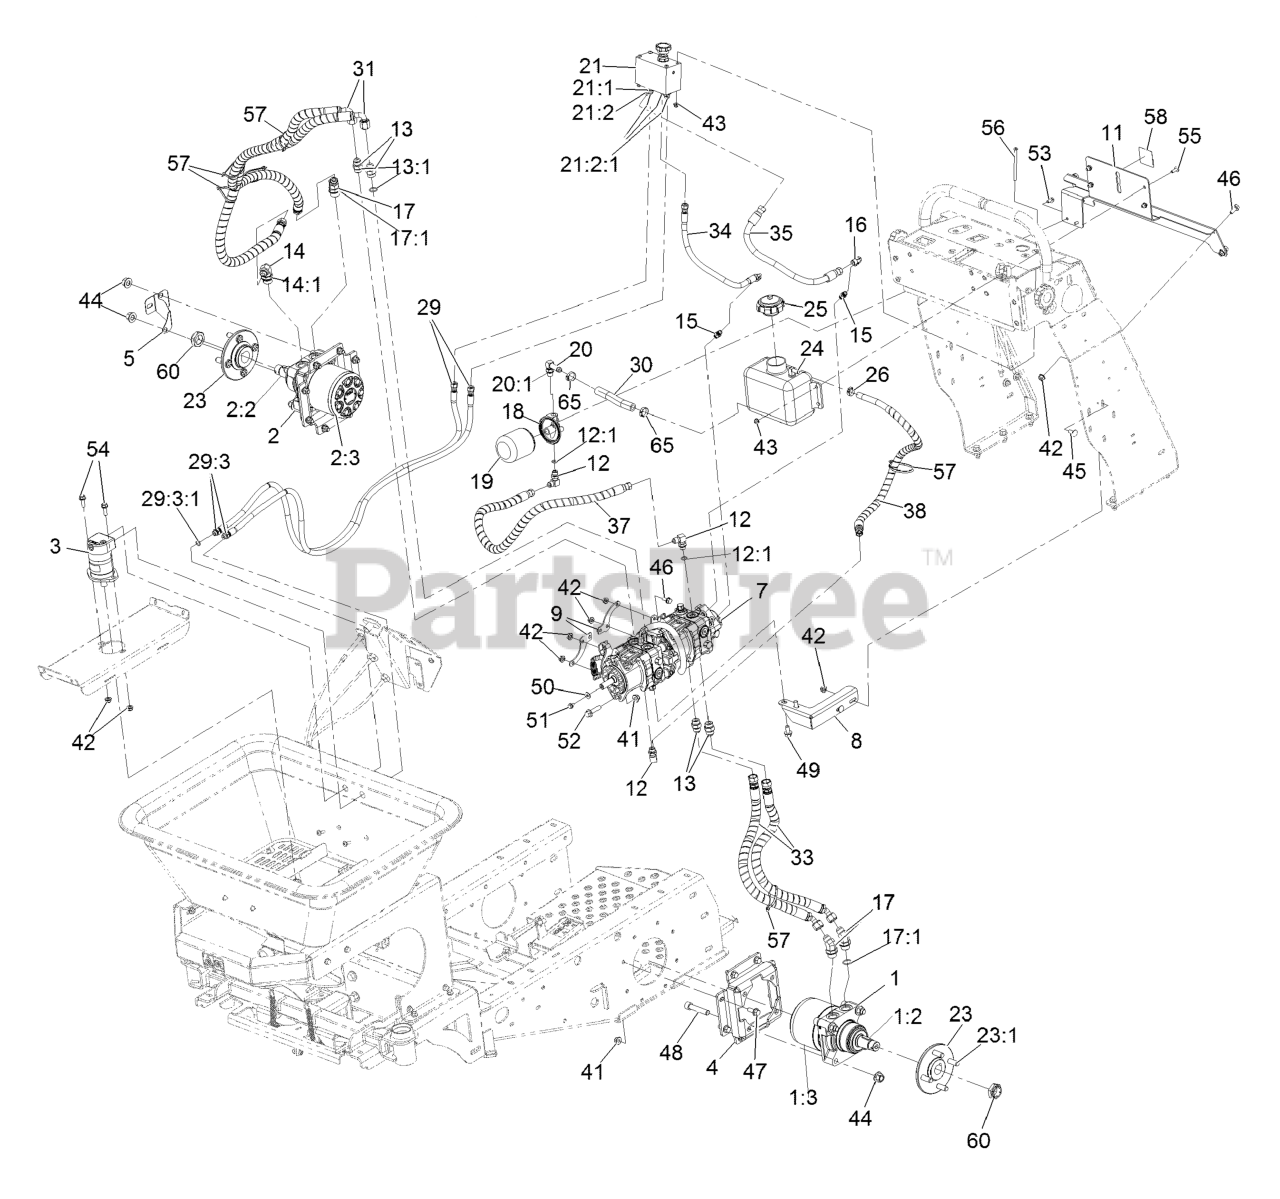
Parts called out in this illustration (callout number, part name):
1	MOTOR, LH WHEEL
1:2	KEY-WOODRUFF
1:3	SEAL KIT
2	MOTOR, RH WHEEL
2:2	KEY-WOODRUFF
2:3	SEAL KIT
3	MOTOR-HYDRAULIC, SPREADER
4	Mount-Motor, Wheel
5	BRACKET-HOPPER, SPEEDOMET
7	PUMP-TANDEM
8	Bracket-Support, Hydro Pump
9	Extension, Hydro Pump
11	Mount, Hydraulic Tank And Filter
12	FITTING-ELBOW, 90 DEG
12:1	O-RING
13	FITTING-STRAIGHT
13:1	O-RING
14	FITTING-90 DEG
14:1	O-RING
15	FITTING-STRAIGHT
16	FITTING-90 SWIVEL
17	FITTING-ELBOW, 45 DEG
17:1	O-RING
18	HEAD-FILTER
19	FILTER-25 MICRON, BI-DIRECTIONAL
20	FITTING-ELBOW, 90
20:1	O-RING
21	Manifold-Flow Control, Hopper
21:2	FITTING-ELBOW, 45 DEG
21:2:1	O-RING
23	HUB-WHEEL
23:1	STUD-1/2-20 X 1.55
24	TANK-HYDRAULIC, PLASTIC
25	Cap-Vented
26	CLAMP-OETIKER, 167
29	Hose ASM-HYD HP
29:3	Fitting-Straight, Rigid
29:3:1	O-RING
30	HOSE-HYDRAULIC
31	HOSE ASM-HYD HP
33	HOSE ASM-HYD HP
34	Hose ASM-HYD HP
35	Hose ASM, HYD LP
37	Hose ASM, HYD LP
38	Hose ASM, HYD LP
41	Nut-Hex Flange
42	Nut-Hex Flange
43	Nut-Hex Flange
44	Nut-Lock 1/2-13
45	SCREW-CARR
46	SCREW-HHF
47	SCREW-HHF
48	Screw-HSH
49	SCREW-HHF
51	SCREW-HHF
52	SCREW-HHF
53	SCREW-HHF
54	SCREW-HHF
55	Screw-Hsbhf
56	Screw-HSBH
57	TIE-CABLE
58	DECAL-OIL
60	LOCKNUT
65	CLAMP-OETIKER, 167
